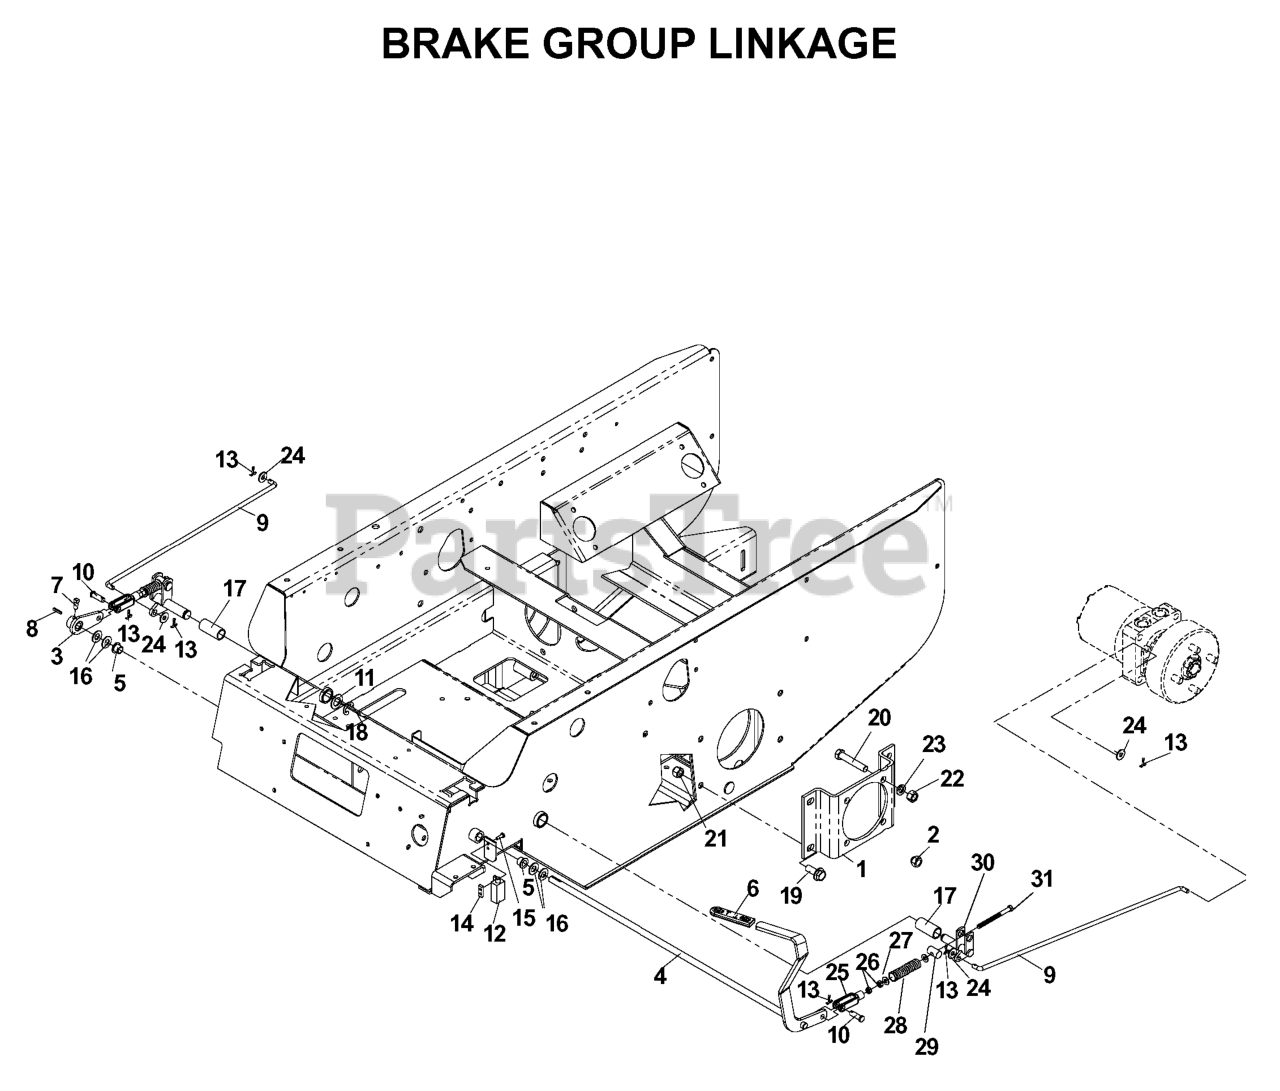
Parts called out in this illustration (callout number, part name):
1	MOTOR STANDOFF - PAINTED
2	LUG NUT 1/2F
3	BRAKE ARM WELDMENT
6	GRIP, PARK BRAKE
7	SCREW 5/16C X 5/8 SQ HEAD
9	BRAKE LINKAGE BAR
10	CLEVIS PIN 3/8 X 1 1/8
13	RP_COTTER PIN 1/8 X 3/4
14	TAPPED PLATE
15	SCREW #10-24 X 5/8
16	WASHER, 7/16 DISC SPRING
17	BRONZE BEARING
18	E RING 3/4
19	HCS 1/2C X 1 1/4 SERRATED HEAD
20	HCS 1/2C X 2 3/4
21	NUT 1/2-13 HEX NYLOC ZD
22	NUT HEX 1/2
23	WASHER 1/2" SPLIT LOCK
24	WASHER 5/16 FLAT
25	YOKE-3/8-24 PLTD
27	WASHER 3/8 SAE FLAT
29	TRUNION PIN
31	HCS 3/8F X SPECIAL
